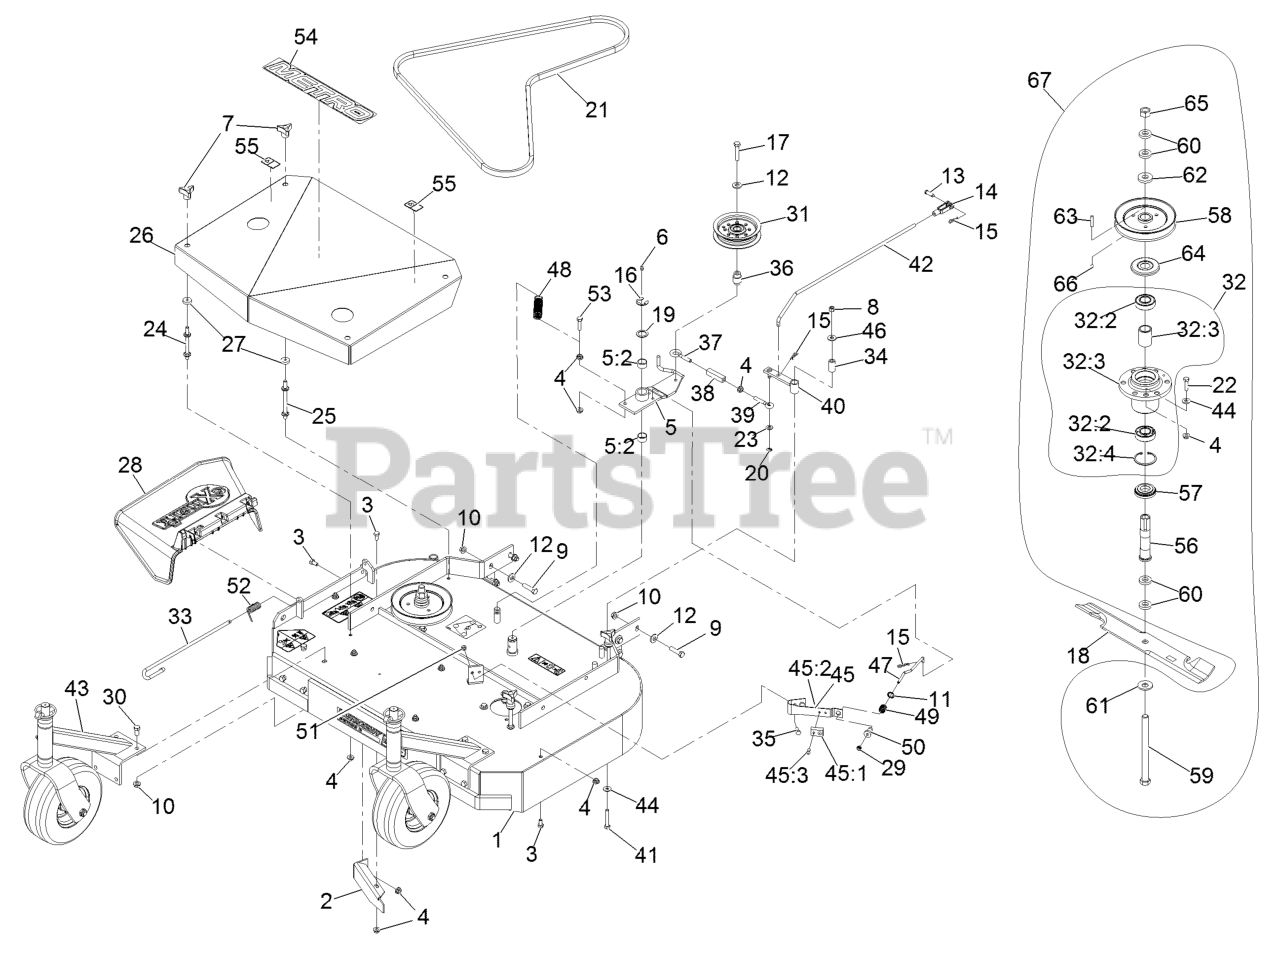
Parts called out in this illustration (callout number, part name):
1	ASM,DECK 36 RIGID
2	BAFFLE-DOGLEG
3	SCREW-HH
5	IDLER ARM ASM
5:2	SLEEVE-BEARING
6	FITTING-GREASE
7	KNOB-3 PRONG
8	NUT-LOCK, NI
9	SCREW-HH
10	NUT-HHF, WHIZ
11	RING-PUSH ON
12	WASHER-BELLEVILLE
13	PIN-CLEVIS
14	YOKE-ADJUSTABLE
15	PIN-COTTER
16	RING-RETAINING, EXT
17	SCREW-HH
19	WASHER-SPINDLE
20	RING-RETAINING, EXT
21	BELT,BLADE METRO 36
22	SCREW-HH
23	WASHER-PLAIN
24	STUD-SHIELD, BELT (SHORT)
25	STUD-SHIELD, BELT (LONG)
26	ASM,SHIELD W/DECALS 36 ME
28	CHUTE DEFLECTOR XRK M056
29	NUT-LOCK, NI
30	SCREW-HH
32	Cutter Housing ASM
32	KIT, CUTTER HOUSING
32:2	BEARING-JACKSHAFT
32:3	SPACER-BEARING
32:4	RING-SNAP
33	PIN-CHUTE
34	TUBE-PIVOT
35	SCREW-HH
36	BUSHING-ENGAGEMENT
37	EYEBOLT-THREAD, LH
38	BODY-TURNBUCKLE
39	EYEBOLT-THREAD, RH
40	ARM-ASSIST, 32/36
41	SCREW-HH
42	ARM-ASSIST, LINKAGE
43	ASM-CASTER MNT W/WEIGHT
44	WASHER-SPRING
45	PAD AND SPRING ASM
46	WASHER-FLAT
47	ROD-BRAKE
48	SPRING-EXTENSION
49	SPRING-COMPRESSION
50	SPACER-FLANGED
51	NUT-LOCK, NI
52	SPRING, TORSION
53	SCREW-HH, SPECIAL
54	Decal-Metro
55	DECAL-WARNING
56	TUBE-SPINDLE, SHORT
57	SPACER-GUARD, BOTTOM
58	SHEAVE
59	SCREW-CAP, HH
61	WASHER-SPRING
62	WASHER-RETAINER, SHEAVE
64	GUARD-BEARING, TOP
65	NUT-HEX
66	SETSCREW
67	ASM, CUTTER HOUSING OUTER
